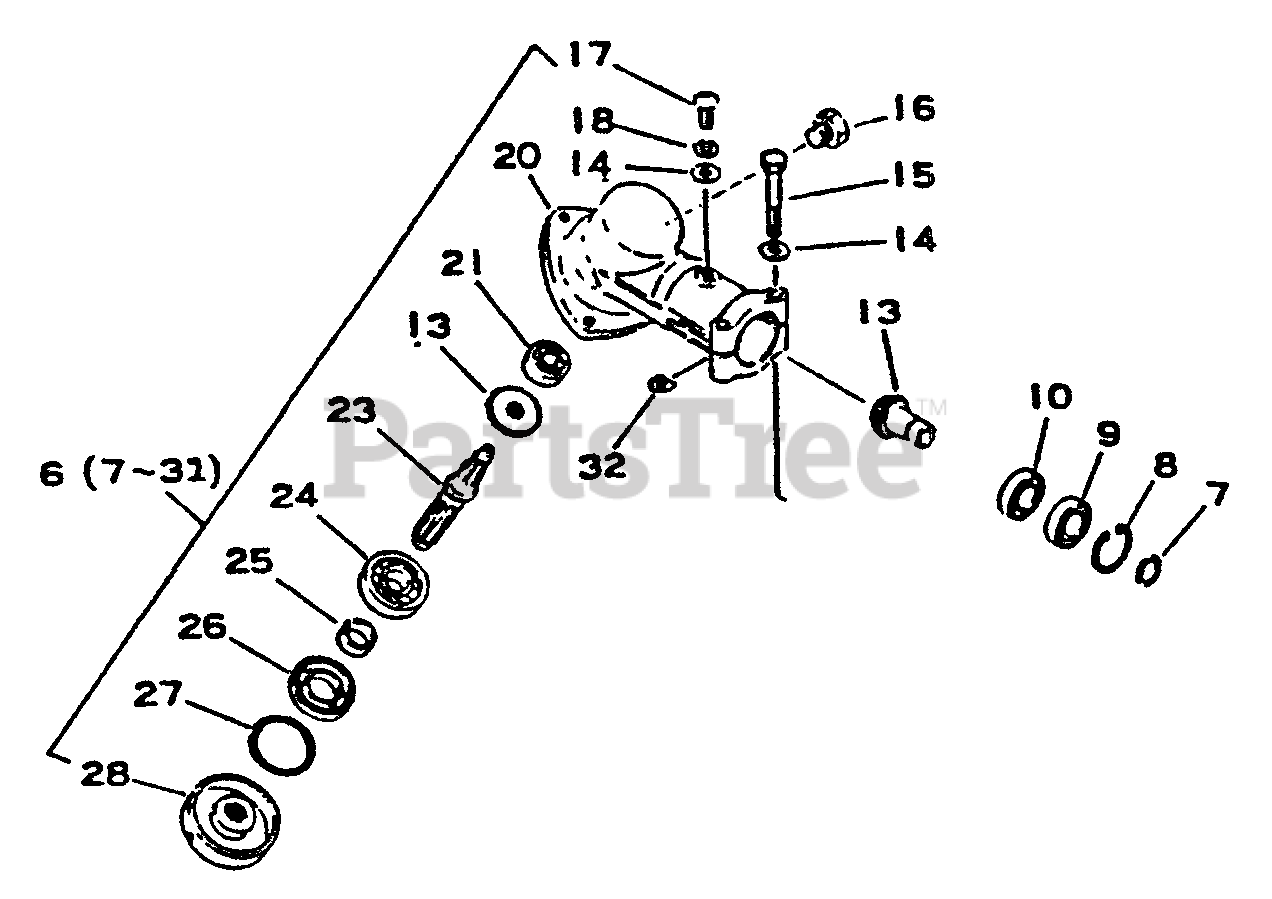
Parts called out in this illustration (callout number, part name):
6	GEAR CASE ASSY
7	RING, RETAINING - 12
8	RING, RETAINING - 22
9	BEARING, BALL - 6900Z
10	BEARING, BALL - 6900
13	GEAR SET - BEVEL
14	WASHER - 5
15	BOLT - 5X35
16	BOLT - 8X8
17	SCREW - 5X10
18	LOCKWASHER - 5
20	CASE, GEAR
21	BEARING, BALL - 609
23	GEAR - SHAFT
24	BEARING, BALL - 6201
26	SEAL, OIL
27	RING, RETAINING - 32
28	ADAPTOR, BLADE - UPPER
